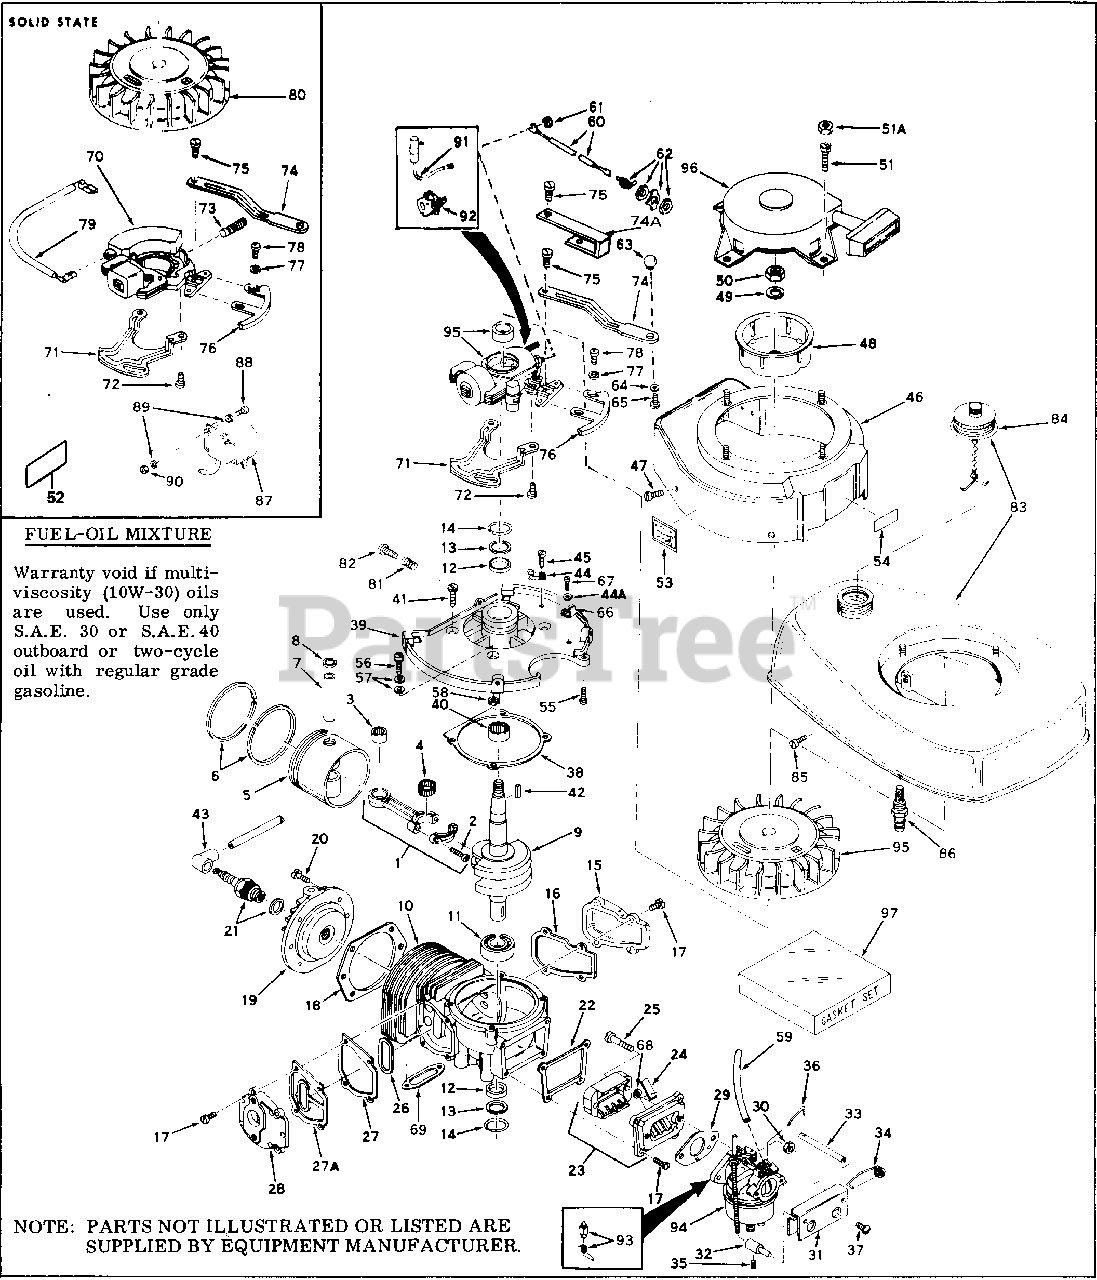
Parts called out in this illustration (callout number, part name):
1	"Rod Assy., Connecting
2	Screw, Connecting rod
3	Bearing, Cartridge
4	Bearing Set, Needle (Set of 32)
6	Ring Set, Piston
7	Pin, Piston
8	Ring, Piston pin retaining
9	Crankshaft
10	Block Assy., Cylinder
11	Bearing, Ball
12	Seal, Crankshaft
13	Retainer, Crankshaft seal
14	Spring, Crankshaft seal retainer
15	Plate, Cover
16	Gasket, Cover plate
17	Screw, Int. Torx, hd., 10-24 x 1/2
18	Gasket, Cylinder head
19	Head, Cylinder
20	Screw, Torx pan hd., 1/4-20 x 3/4
21	Plug, Spark
22	Gasket, Reed plate
23	Plate Assy., Reed
25	Screw, 1/4-28 x 1-1/4 Pan hd. whiz-lo ck
26	Gasket, Port
27	Gasket, Adapter cover
28	Cover, Adapter
29	Gasket, Carburetor
30	Nut, Flange whiz-lock, 1/4-28
31	Bracket, Control
32	Rod, Idle adjustment
33	Rod, Choke
34	Spring, Choke return
35	Screw, 6-32 x 3/16 Hex socket hd.
36	Link, Choke shaft
37	Screw, Pan hd. Torx, 10-32 x 3/8
38	Gasket, Shroud base
39	Base Assy., Shroud
40	Bearing, Needle
41	Screw, 1/4-20 x 5/8 Flat hd.
42	Key, Flywheel
43	Cover, Spark plug
44	Clip, Cable
44A	Washer, Flat No. 10
45	Screw, Hex washer hd., 1/4-20 x 3/8
46	Shroud, Air
47	Screw, Hex washer hd., 1/4-20 x 3/8
48	Cup, Starter
49	Washer, Lock (7/16) (Split)
50	Nut, Flywheel
51A	Nut, Whiz-lock (1/4-28)
53	Decal, Instruction
54	Decal, Instruction
55	Screw, Torx pan flex hd., 10-24 x 7/8
63	Knob, Control
64	Washer, 1/4 lock
65	Screw, Torx pan hd., 1/4-20 x 5/8
66	Stop, Control lever
67	Screw, Pan flex hd., 10-24 x 3/8
73	Screw Assy., Friction
74	Lever, Control
75	Screw, Pan flex hd., 10-24 x 3/8
76	Cam, Throttle
77	Washer, Flat
78	Screw, 6-32 x 3/8 Torx pan flex hd.
83	Tank Assy., Fuel (Incl. No. 84)
91	Condenser
92	Contact Assy., Breaker
93	Inlet Needle & Spring Assy.
94	Carburetor
96	Starter, Rewind
97	Gasket Set
